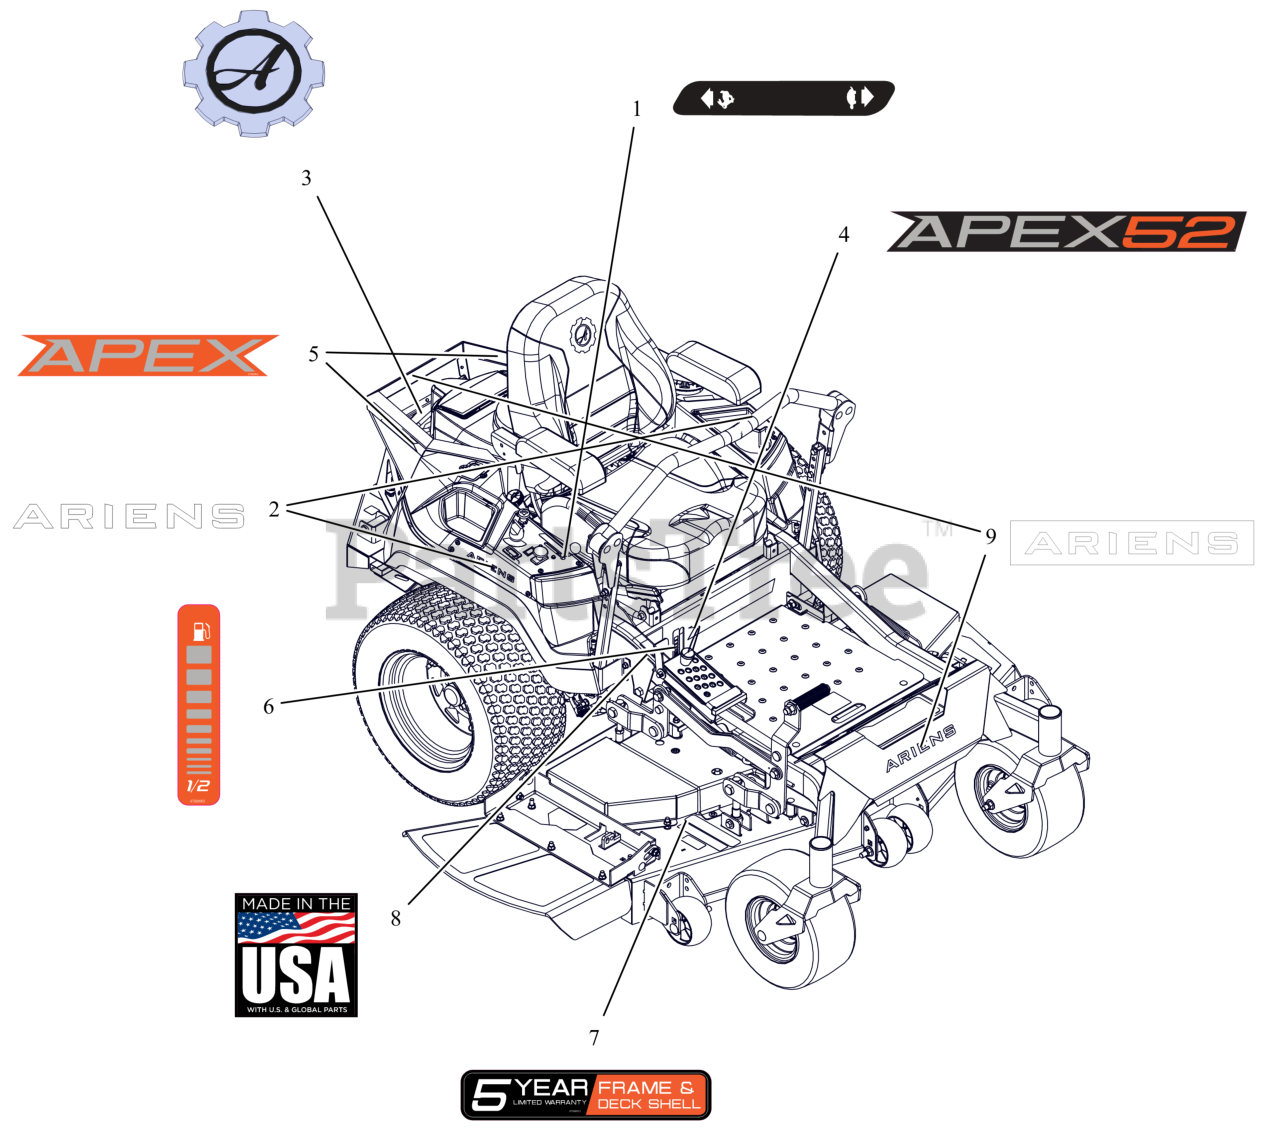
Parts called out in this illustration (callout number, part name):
1	DECAL, DASH DECAL
2	DECAL, ARIENS (6.50")
3	DECAL, ARIENS-GEAR BADGE -THK
4	DECAL, 52" APEX KICKPLATE
5	DECAL, APEX FENDER
6	DECAL, ARIENS FUEL LEVEL
7	DECAL, DECK 5 YEAR-ARIENS
8	DECAL, MADE IN USA
9	DECAL - ARIENS 9.625"
